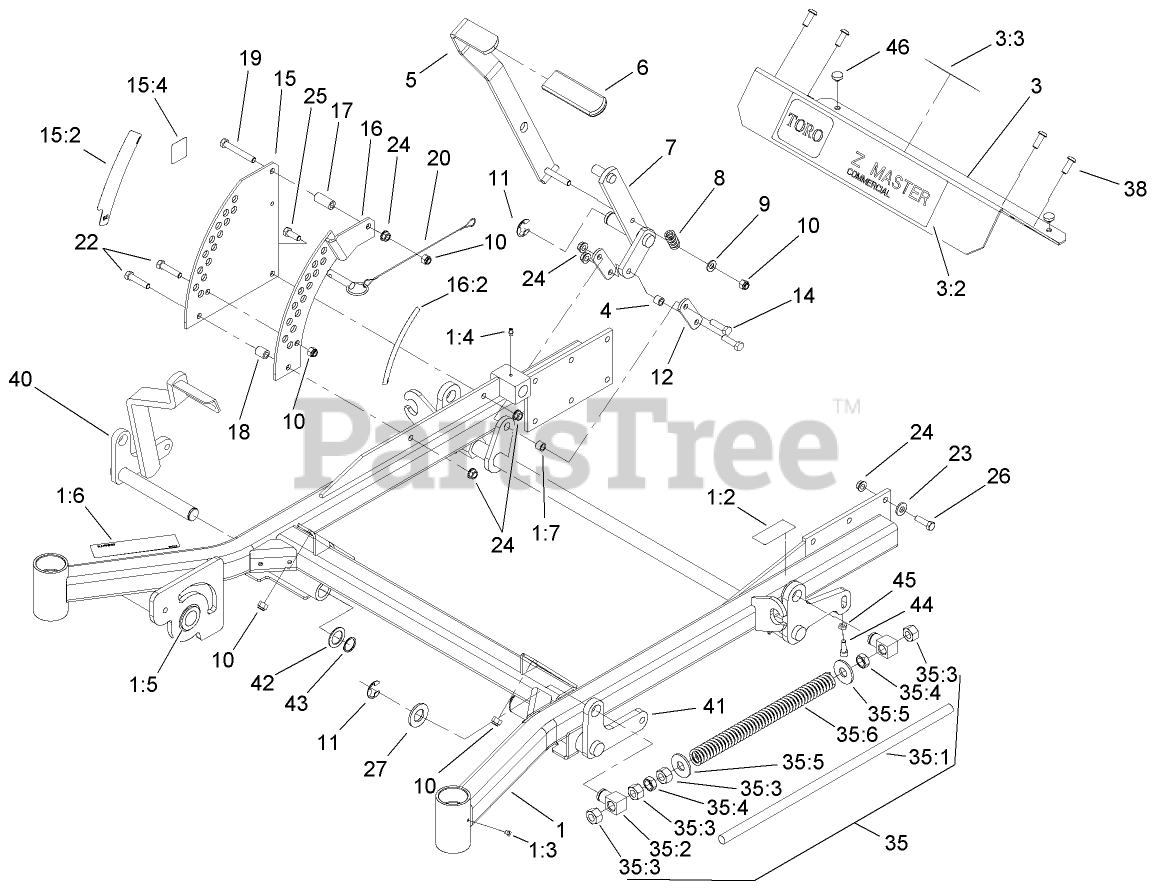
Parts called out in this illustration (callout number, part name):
1	FRAME ASM
1:2	DECAL-BRAKE, PARKING
1:4	FITTING-GREASE
1:5	BUSHING
1:6	DECAL-WARNING
1:7	Bushing
3	FOOTREST
3:3	DECAL-DANGER, SLOPE
4	Bushing
5	LEVER-LIFT
6	GRIP-LEVER, LIFT
7	ARM-LIFT, DECK
8	SPRING-COMPRESSION
9	WASHER-FLAT
10	NUT-LOCK, NI
11	RING-RETAINING, EXT
12	ARM-LIFT, DECK
14	SCREW-HH
15	PLATE-DECK LIFT, OUTER (CE)
15:2	DECAL-HEIGHT, DECK
15:4	DECAL-NOISE
16	PLATE-DECK LIFT, INNER (CE)
16:2	DECAL-HEIGHT, DECK
17	BUSHING-LEVER, LIFT
18	BUSHING-LEVER, LIFT
19	SCREW-HH
20	Hitch Pin ASM
22	SCREW-HH
23	WASHER-BELLEVILLE
24	NUT-HHF, WHIZ
25	SCREW-HH
26	SCREW-HH
27	WASHER-FLAT
35	Front Frame Spring ASM
35:1	ROD-LIFT, DECK
35:2	SWIVEL-DECK MOUNT, REAR
35:3	NUT-HEX
35:4	NUT-JAM
35:5	WASHER-FLAT
35:6	SPRING-SUPPORT, DECK
38	SCREW-HSBH
40	LIFT-DECK, RH FRONT
41	LIFT-DECK, LH
42	WASHER-SPACER
43	RING-RETAINING
44	SCREW-HSH
45	NUT-JAM
46	BUMPER
